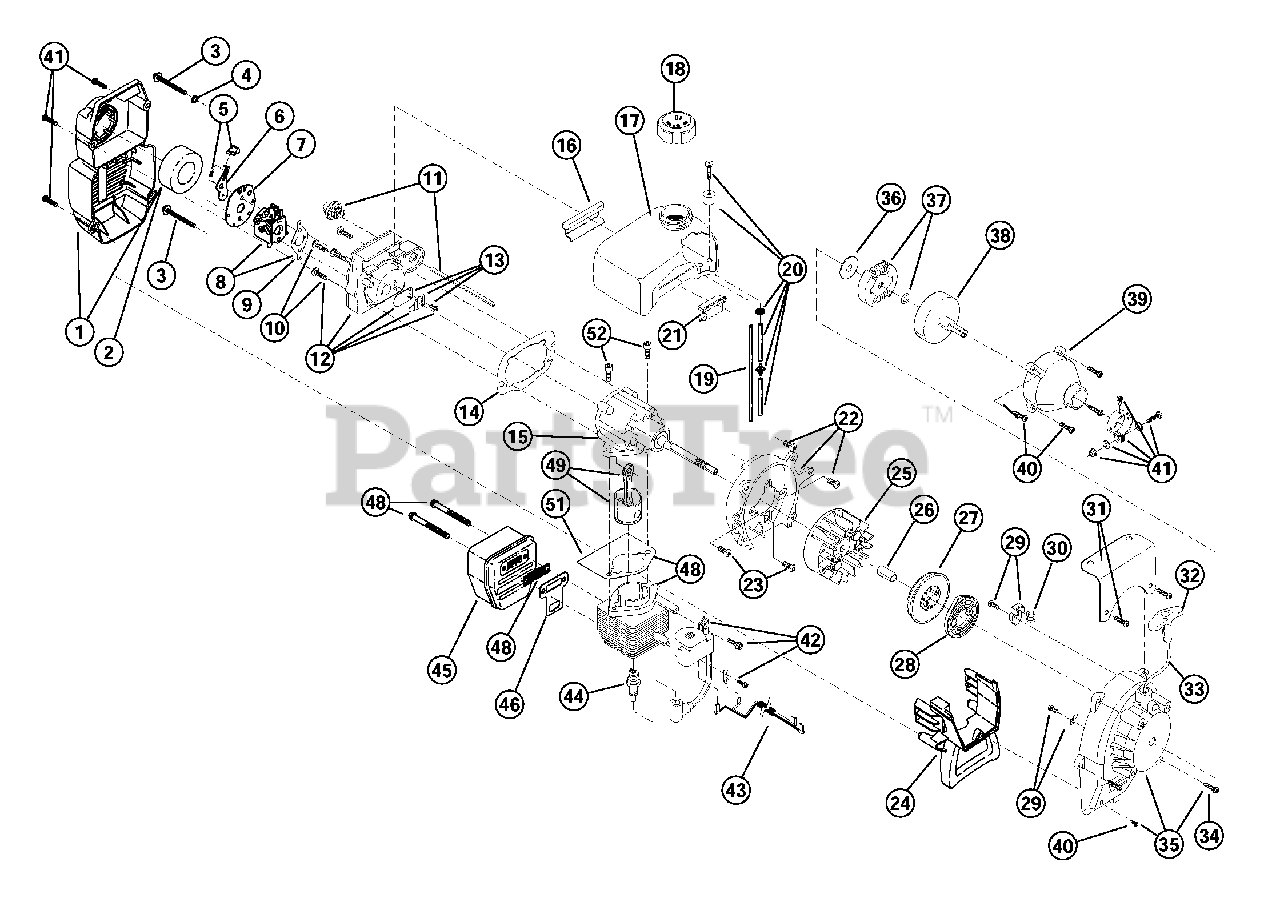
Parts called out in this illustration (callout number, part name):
1	Air Cleaner/Muffler Cover Assembly
2	Air Cleaner Filter
3	Carburetor Mounting Screw Assembly
4	Wavey Washer
5	Choke Lever Assembly
6	Choke Knob and Screw
7	Choke Lever and Plate
8	Carburetor Assembly
9	Carburetor Gasket
10	Carb Mount Screw
11	Primer and Hose Assembly
12	Carb Mount Assembly
13	Reed Assembly
14	Carburetor Mount Gasket
15	Crank Case Service Assembly
16	Rear Mounting Pad
17	Fuel Tank Assembly
18	Fuel Cap Assembly
19	Fuel Return Line
20	Fuel Line Assembly
21	Front Mounting Pad
22	Shroud Assembly
23	Shroud Screw
24	Shroud Extension and Stand
25	Flywheel Assembly
27	Recoil Pulley Assembly
28	Recoil Spring
29	Pulley Retainer Assembly
30	Rope Guide
31	Fuel Tank Guard Assembly
32	Pull Handle
34	Housing Screw
35	Starter Housing Assembly
36	Clutch Washer
37	Clutch Rotor Assembly
38	Clutch Drum Assembly
39	Clutch Cover Assembly
40	Cover Screw
41	Upper Clamp Assembly
42	Module Assembly
43	Wire Lead
44	Spark Plug
45	Muffler Assembly
46	Exhaust Gasket
47	Spark Arrestor
48	Muffler Mounting Bolt Assembly
49	Cylinder Assembly
50	Piston and Rod Assembly
51	Cylinder Gasket
52	Cylinder Bolt
